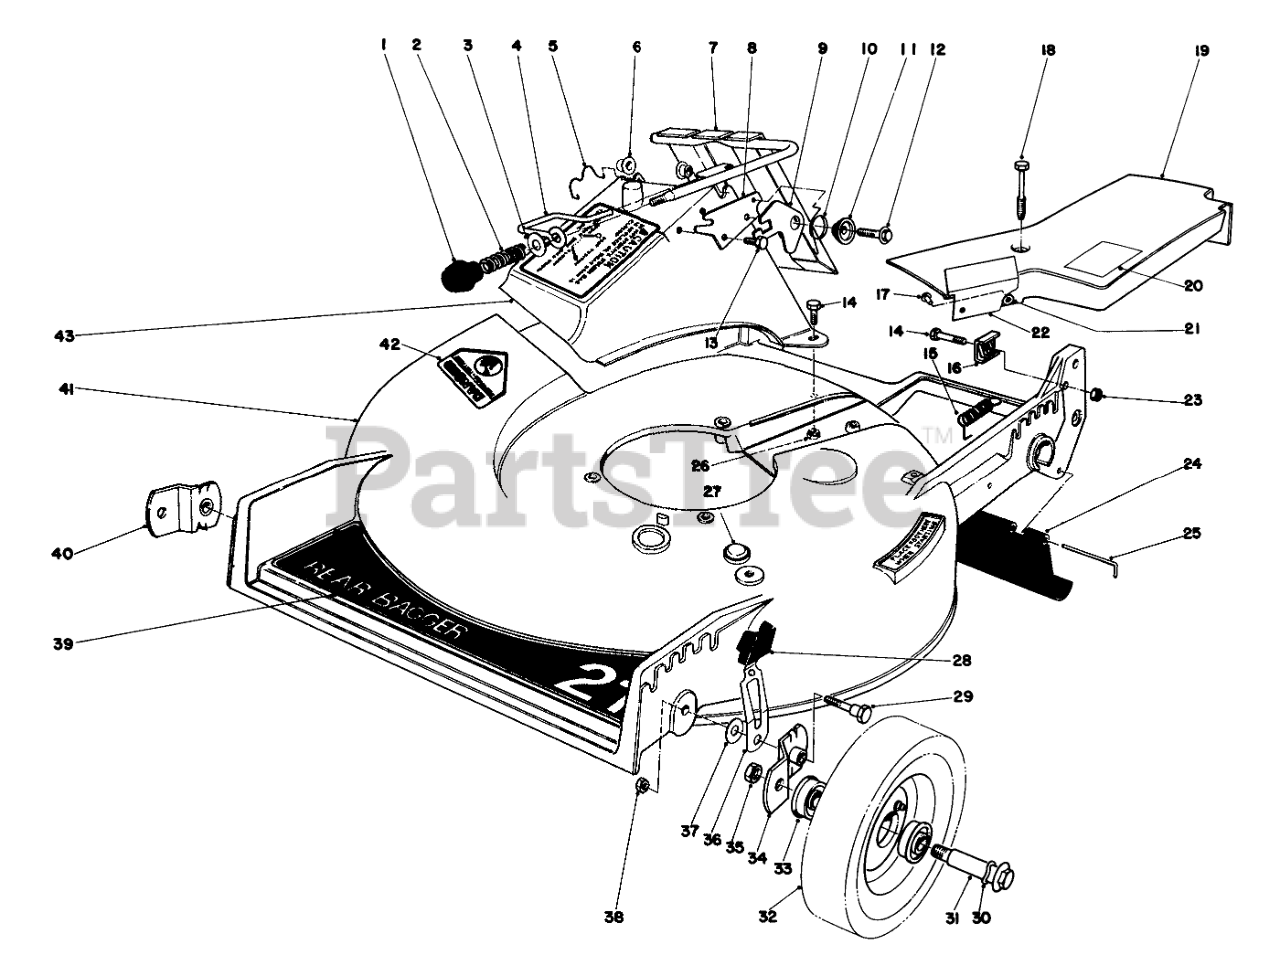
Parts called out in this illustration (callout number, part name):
2	COMPRESSION SPRING
3	WASHER-FLAT
4	DOOR LATCH
5	DOOR RETAINER
6	BUSHING-NYLON
7	DOOR & HANDLE WA
8	DOOR LATCH PLATE
9	Latch-Door
10	Spring-Torsion
11	Latch Spacer
12	Screw
13	SCREW-HWH
14	SCREW-HH
15	IDLER SPRING
16	CLAMP-CABLE
17	RIVET-HEAD, FLAT
18	SCREW-HHFTF
19	Belt Cover (Incl. Ref. #17 & 21-22)
20	Sticker Grease
21	WASHER-FLAT
22	HEAT SHIELD
23	NUT-JAM
24	SHIELD - TRAILING
25	Rod Shield
26	NUT-LOCK, NI
28	KNOB-ARM
29	PIVOT SCREW
30	SPRING WASHER
32	Wheel & Tire Assembly (Incl. Ref. #33)
33	BEARING-BALL
34	PIVOT ARM ASM A
35	Nut
36	SPRING ARM ASM (R&S)
37	WASHER-PIVOT
38	Nut
39	Decal-Deck
40	PIVOT ARM ASM B
41	Housing
42	DECAL-DANGER
43	DISCHARGE CHUTE B
